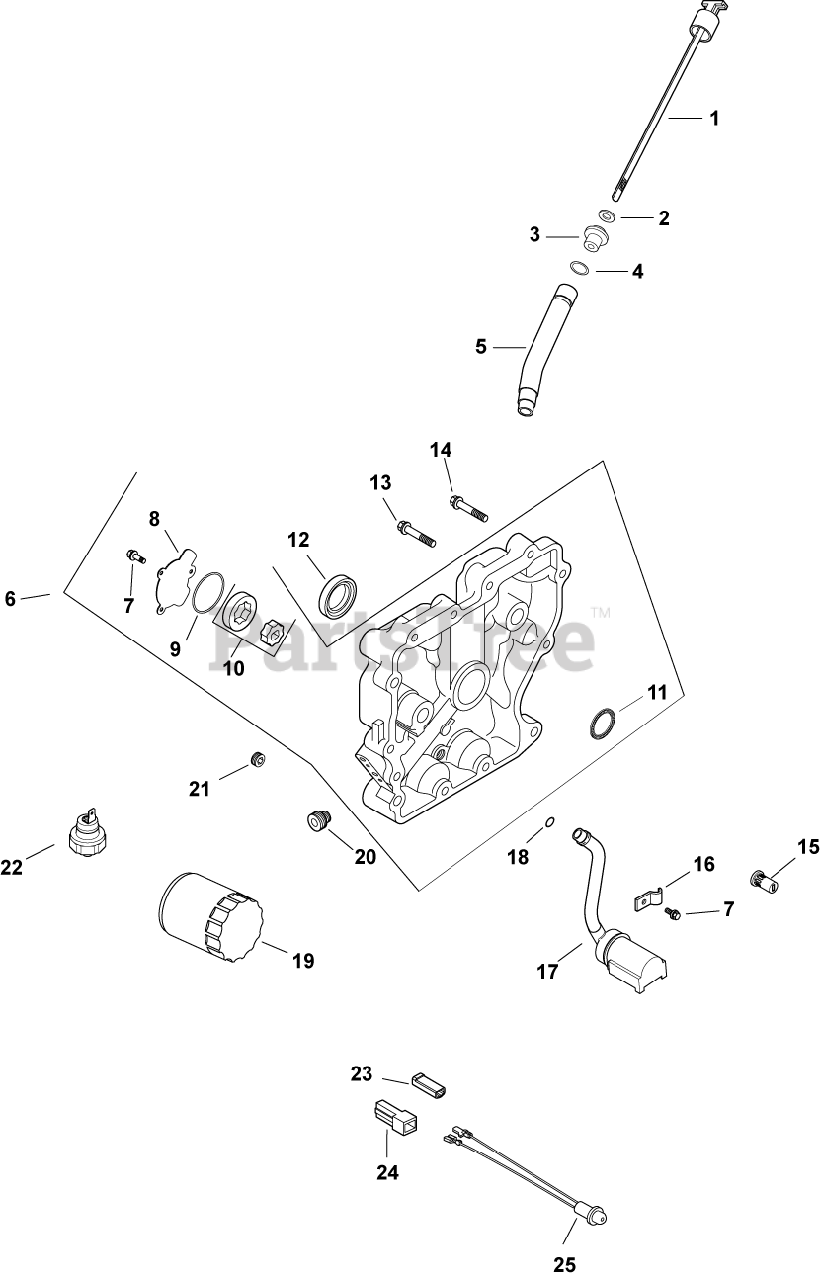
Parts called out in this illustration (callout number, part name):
3	SEAL USE 25 032 13-S
5	TUBE, OIL FILL
6	PLATE, CLOSURE & BEARING
7	SCREW,FLG THD FRM M5X0.8X16-(#25086398S)
8	COVER, OIL PUMP
9	O-RING (1.78" DIA)
10	PUMP ASSEMBLY, OIL
11	BEARING, CRANKSHAFT
12	SEAL, OIL
13	SCREW, FLG M8X1.25X45
14	SCREW, HEX FLANGE -USE 24 086 17-S
15	VALVE, OIL PRESSURE RELIEF
17	KIT, OIL PICK-UP
18	O-RING (.5" DIA)
19	OIL FILTER
20	NIPPLE, OIL FILTER
21	PLUG, CTSK PIPE 1/8"
22	SENSOR, OIL PSI
23	CONNECTOR (1 CONTACT)
24	CONNECTOR
